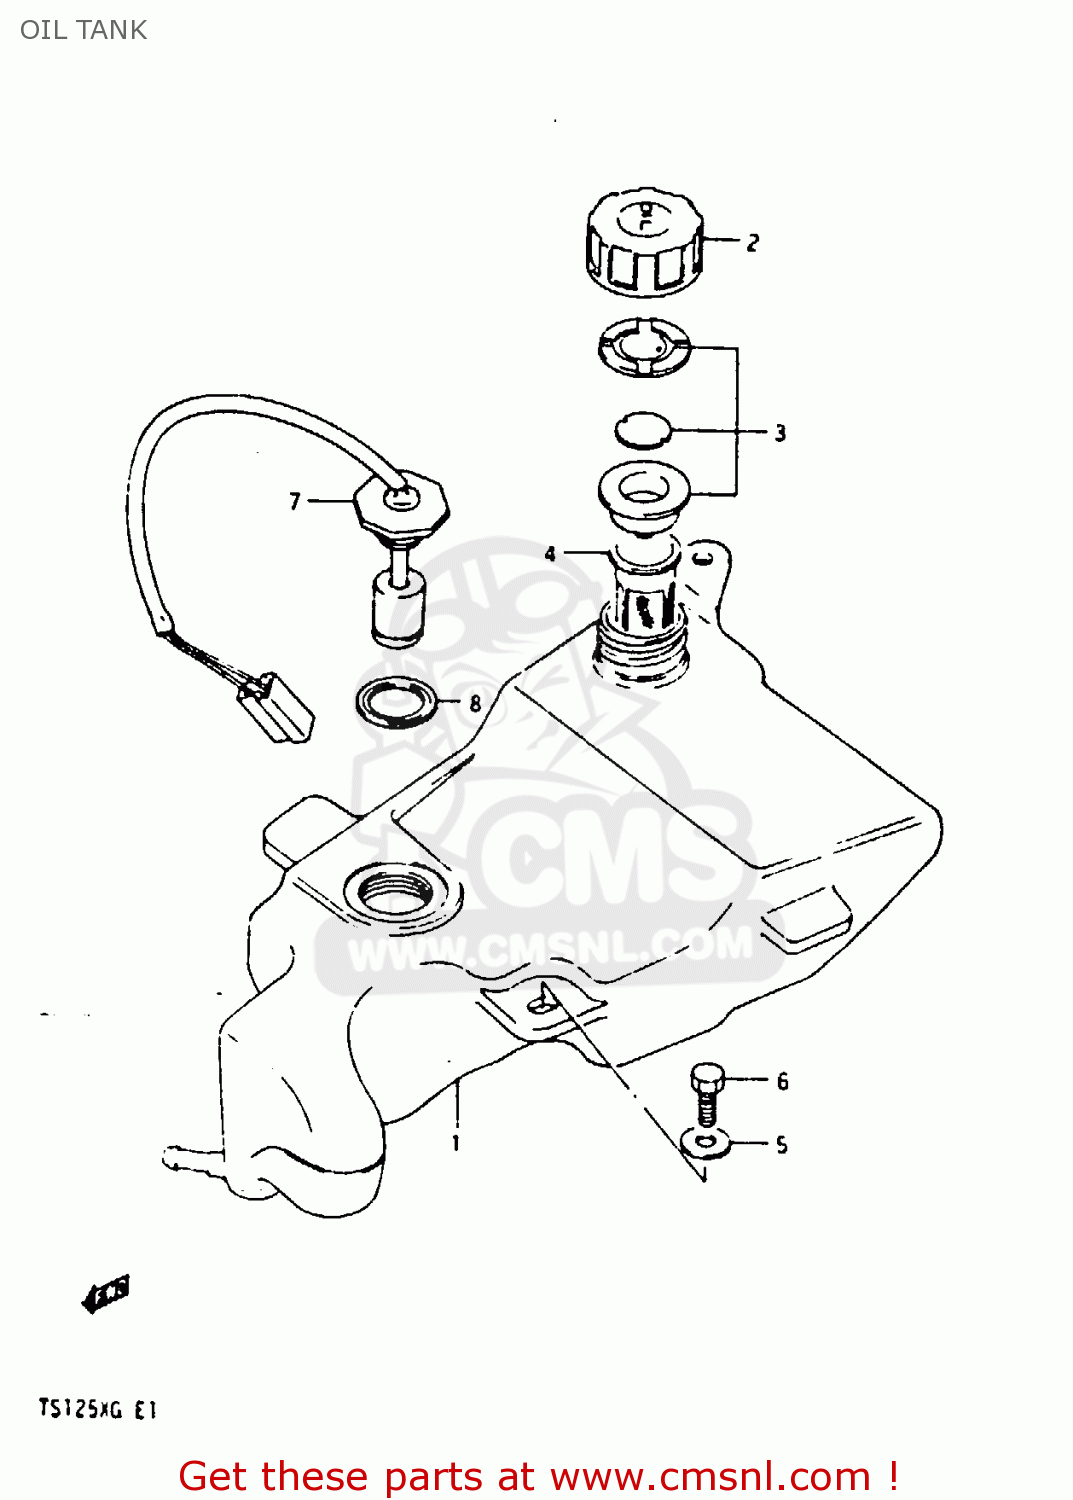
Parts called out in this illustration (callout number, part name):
1	TANK, OIL
2	CAP,OIL TANK
3	GASKET SET (NAS)
4	FILTER,OIL TANK INLET
5	WASHER
6	BOLT, UPPER
7	SWITCH ASSY, OIL LEVEL
8	GASKET (NAS)
